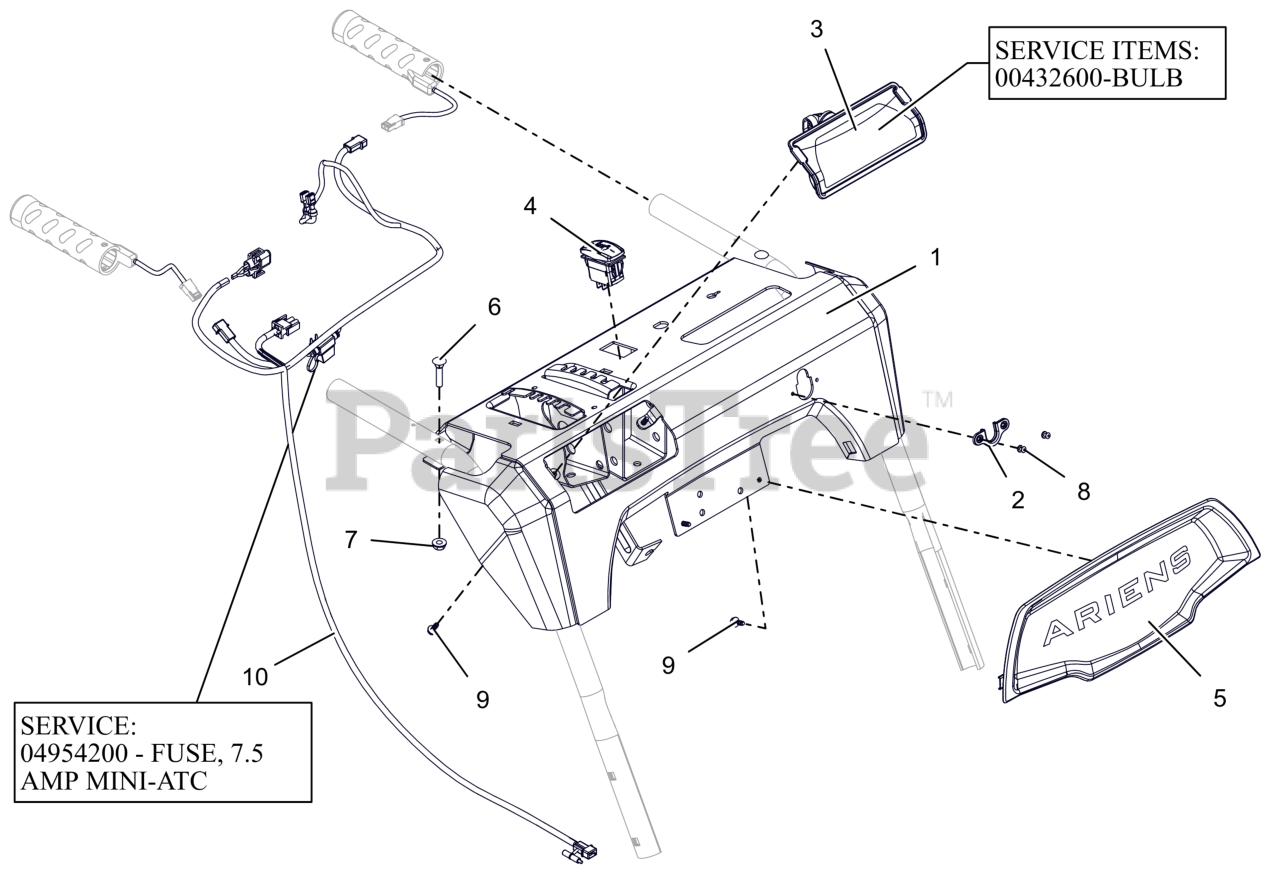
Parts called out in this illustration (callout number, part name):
1	PANEL, CONTROL-EFI QT W/DECAL
2	GROMMET, CABLE, QUICK TURN 2
3	HEADLIGHT ASY, HALO 20W 2SHOT
3	BULB, LIGHT-HALOGEN 20W
4	SWITCH,ROCKER SPST-ON/OFF
5	BEZEL, DASH - ARIENS LG DASH
6	BLT-RDHDXLSQNK.25-20X1.25 G5ZC
7	NUT-LK-CTR-FLG .25-20 ZC120
8	RVT-POP #43 .125X.313 STL ZINC
9	SCR, PLASTIC #10X.50
10	HARNESS,LIGHT&WARMER - EFI
10	FUSE, 7.5 AMP MINI-ATC
